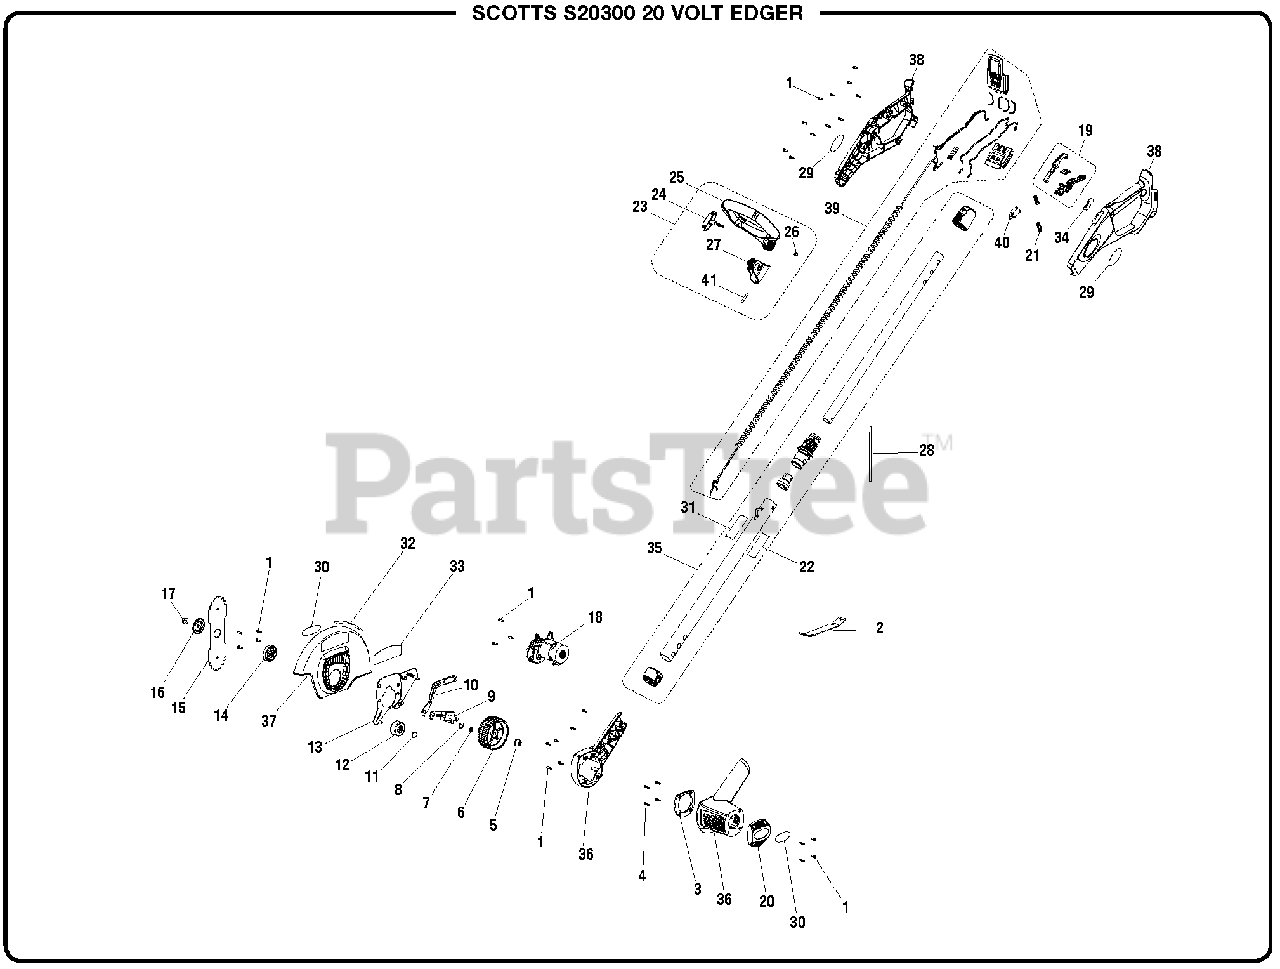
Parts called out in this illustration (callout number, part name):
1	Screw (M4 x 14 mm)
3	Baffle Plate
4	Screw (M3.5 x 14 mm, Pan Hd.)
7	C-Ring (OD10.59 x ID8.94)
9	Pivot Bracket
10	Depth Adjustment Lever
12	Edger Depth Restrictor Wheel
13	Skidplate Bracket Assembly
14	Flanged Washer
15	Edger Blade
16	Cupped Washer
17	Lock Nut (M8)
18	Motor & Gear Box Assembly
19	Switch Trigger and Lock-Out Lever Assembly
20	Motor Cap
21	Compression Spring
22	Warning Label (French/Spanish)
23	Auxilary Handle Assembly
26	Hex Nut (M6)
27	Handle Bracket
28	Holding Pin Tool
29	Logo Label
30	Logo Label (Guard)
31	Warning Icon Label (Boom)
32	Warning Icon Label (Guard)
33	Data Label
34	Fuel Gauge Label
35	Pole Assembly
36	Motor Housing Assembly
37	Blade Guard
38	Handle Assembly
39	Wiring Harness
41	Rubber Plate
